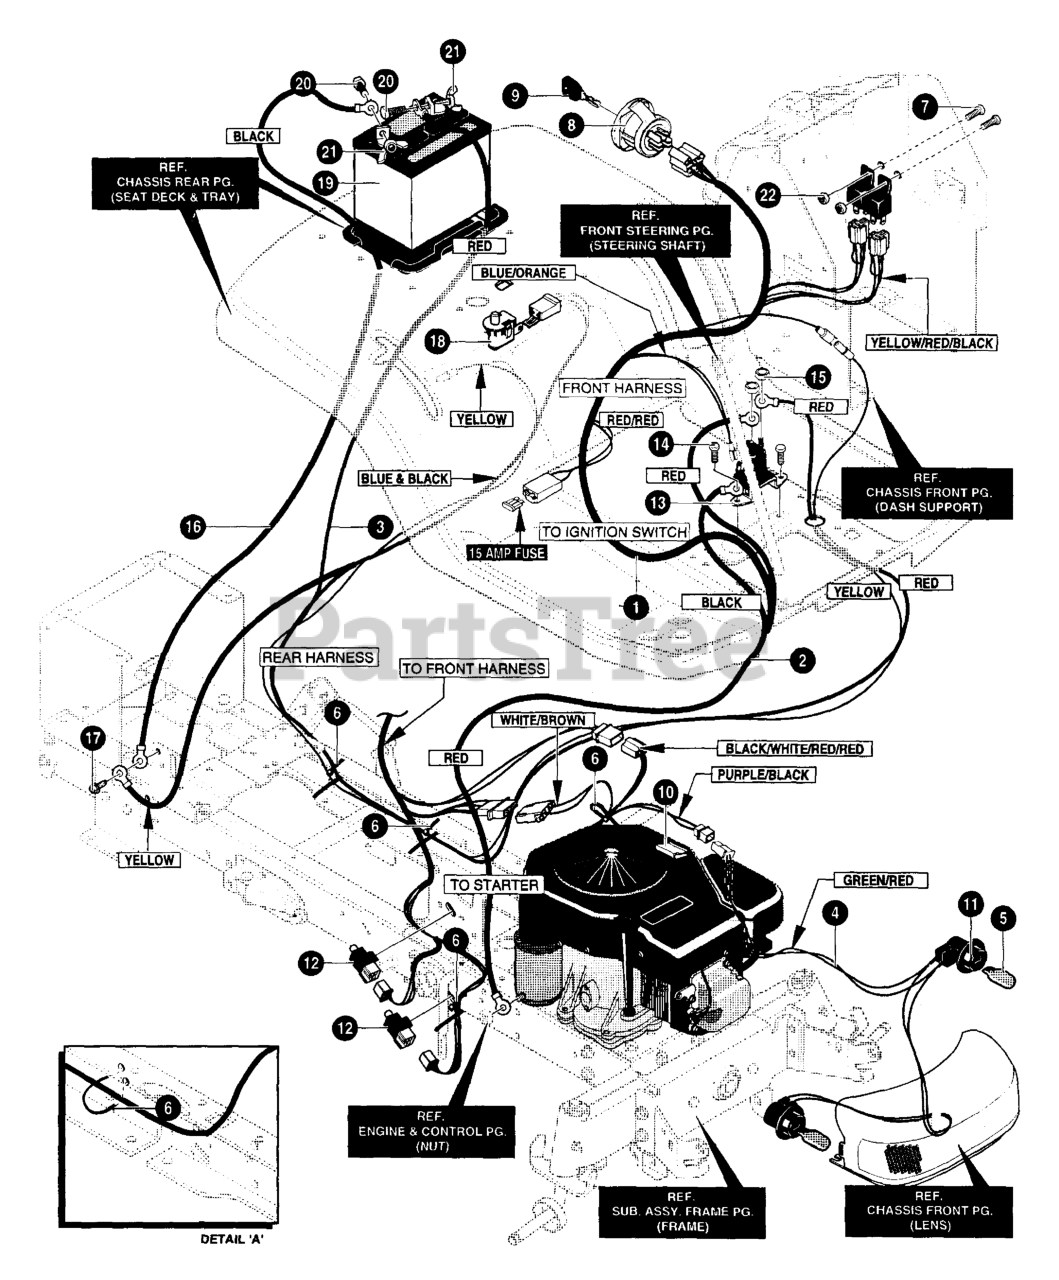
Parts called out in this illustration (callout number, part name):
1	HARNESS, WIRE 16HP KOHLER
2	WIRE, LEAD SOLENOID TO STARTER
3	WIRE HARNESS, REAR
4	WIRE HARNESS, HEADLIGHT
5	BULB, HEADLIGHT 1156
6	TIE, CABLE BLACK NYLON 5.62L
7	SCREW, 10-24X.50 WAHHMA
8	SWITCH, IGNITION DELTA 7 TERM
9	KEY,IGNITION GENERIC DELTA
10	WIRE CLIP
11	SOCKET, LAMP
12	SWITCH LIMIT DELTA
13	SOLENOID
14	SCREW,HHWATAP 1/4X.50
15	NUT, 1/4-20 HEXNYL 15X116
16	WIRE, GROUND (24X32)
17	SCREW, HHWATAP 1/4 X.50
18	SWITCH, SEAT
19	BATTERY 12V 7 PLATE
20	BOLT, 1/4-20X.63CAR
21	NUT, WING 1/4-20 NC (14X79)
22	NUT #10-24 KEPS
